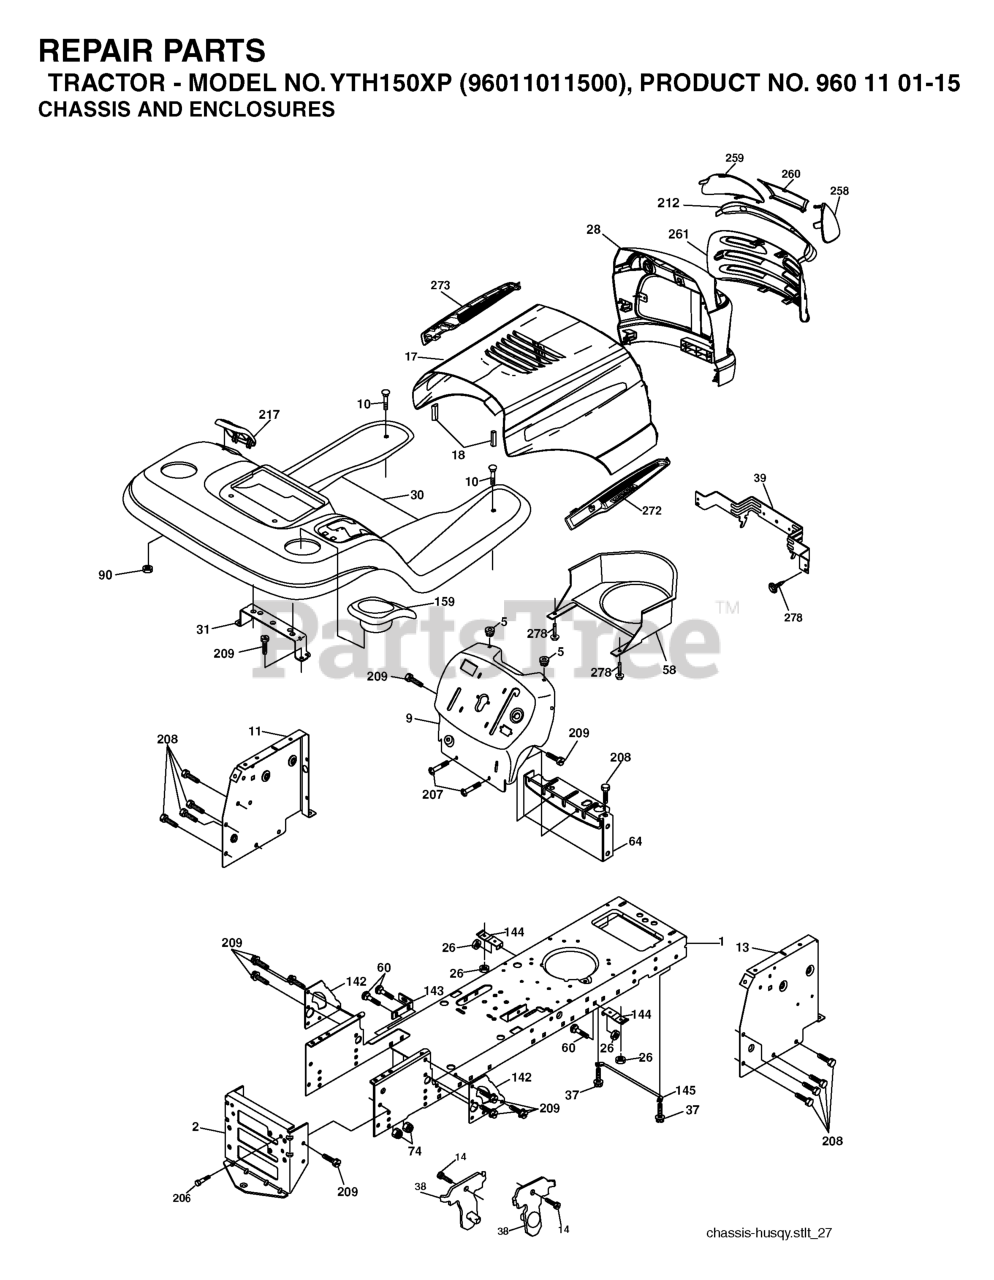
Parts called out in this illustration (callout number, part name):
1	CHASSIS STAMPING
2	DRAWBAR, 12GA
5	BUMPER.RUBBER.HOOD
9	FENDER.STL.W/O CUPHLDR.ROS.422
10	BOLT D
11	PANEL.DASH.LH.LTX
13	PANEL ASM, DASH RH
14	SCREW LT
17	VENT.HOOD.LASER.III
18	BUMPER.HOOD.LARGE.1.75"
26	NUT
30	FENDER
31	BRACKET.SUPPORT.FENDER
37	Screw 5/16-18 x 1/2 Hex, Self Tapping 5/16-18 x 1/2
38	BRACKET.ASM.PIVOT.MOWER.REAR
39	BRACKET PIVOT LASER
60	Bolt - Rd. Hd. Sq. Neckiage 3/8 16 x 3/4
64	DASH LOWER
90	NUT.PUSH.3/16
142	PLATE REINFORCEMENT
143	BRACKET, SWAYBAR CHASSIS
144	BRKT, FOOT REST
145	ROD PIVOT CHASSIS/HOOD
159	CUPHOLDER
206	SHOULDER BOLT 5/16-18TT
207	SCREW, 5/16-18 X 1/2
208	SCREW 3/8-16X1/2
209	SCREW, 3/8-16X3/4
212	INSERT.LENS.REFLECTIVE
217	CONSOLE FUEL WINDOW
258	LENS LH
259	LENS LH
260	COVER.LENS.HUSQ.LASER
272	VENT.HOOD.LASER.
273	VENT.HOOD.LASER.
278	SCREW
